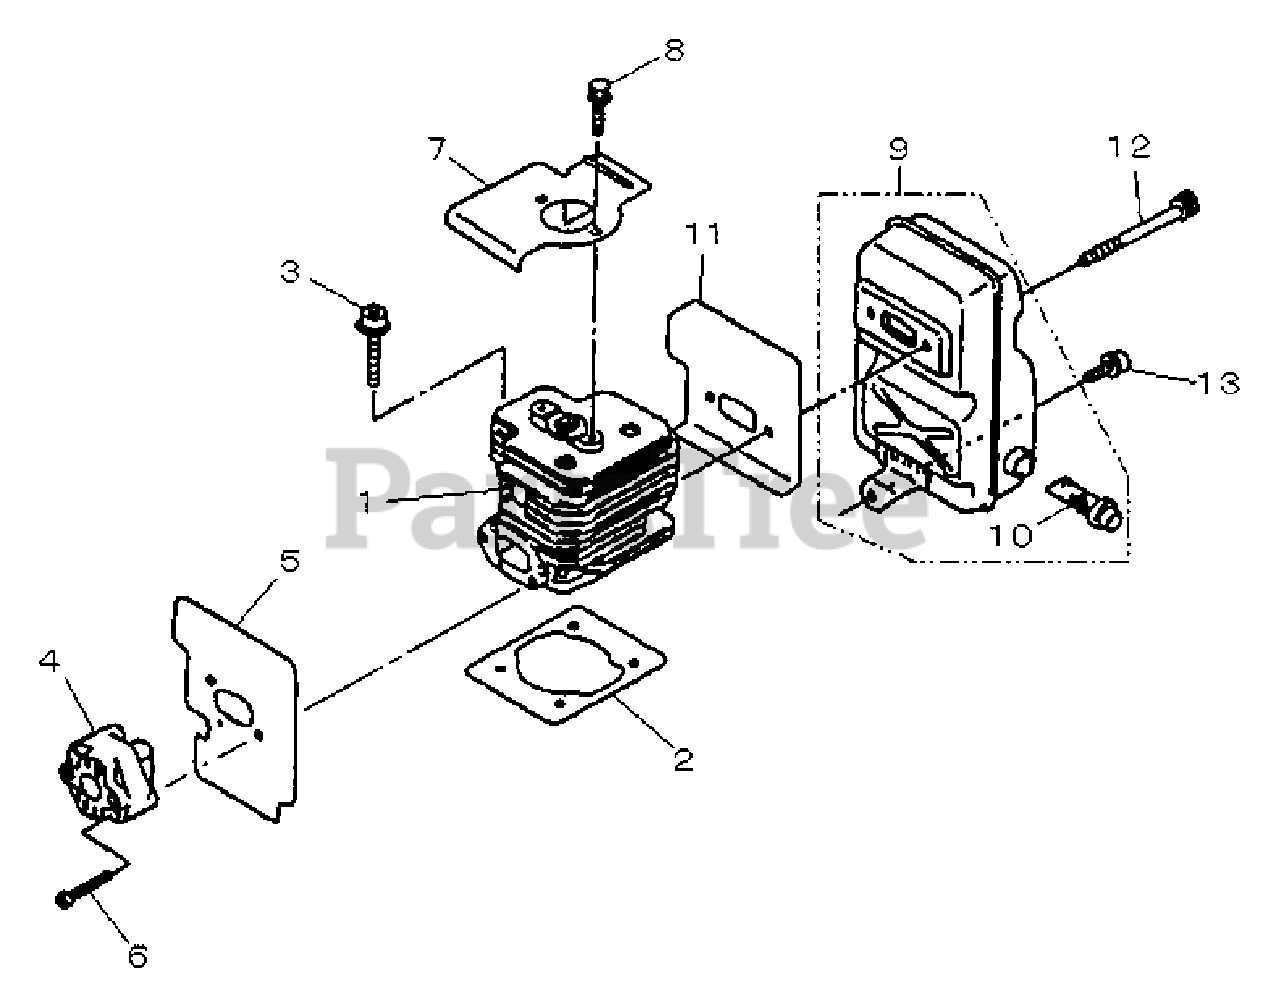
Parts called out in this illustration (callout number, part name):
1	CYLINDER
2	GASKET, CYLINDER
3	BOLT - 5X22
4	INSULATOR
5	GASKET, INTAKE
6	SCREW - 5X35
7	SHIELD, CYLINDER
9	MUFFLER ASSY
10	SCREEN, SPARK ARRESTOR
11	GASKET, EXHAUST
12	SCREW - 6X70
13	BOLT - 6X12 -- FLANGE
